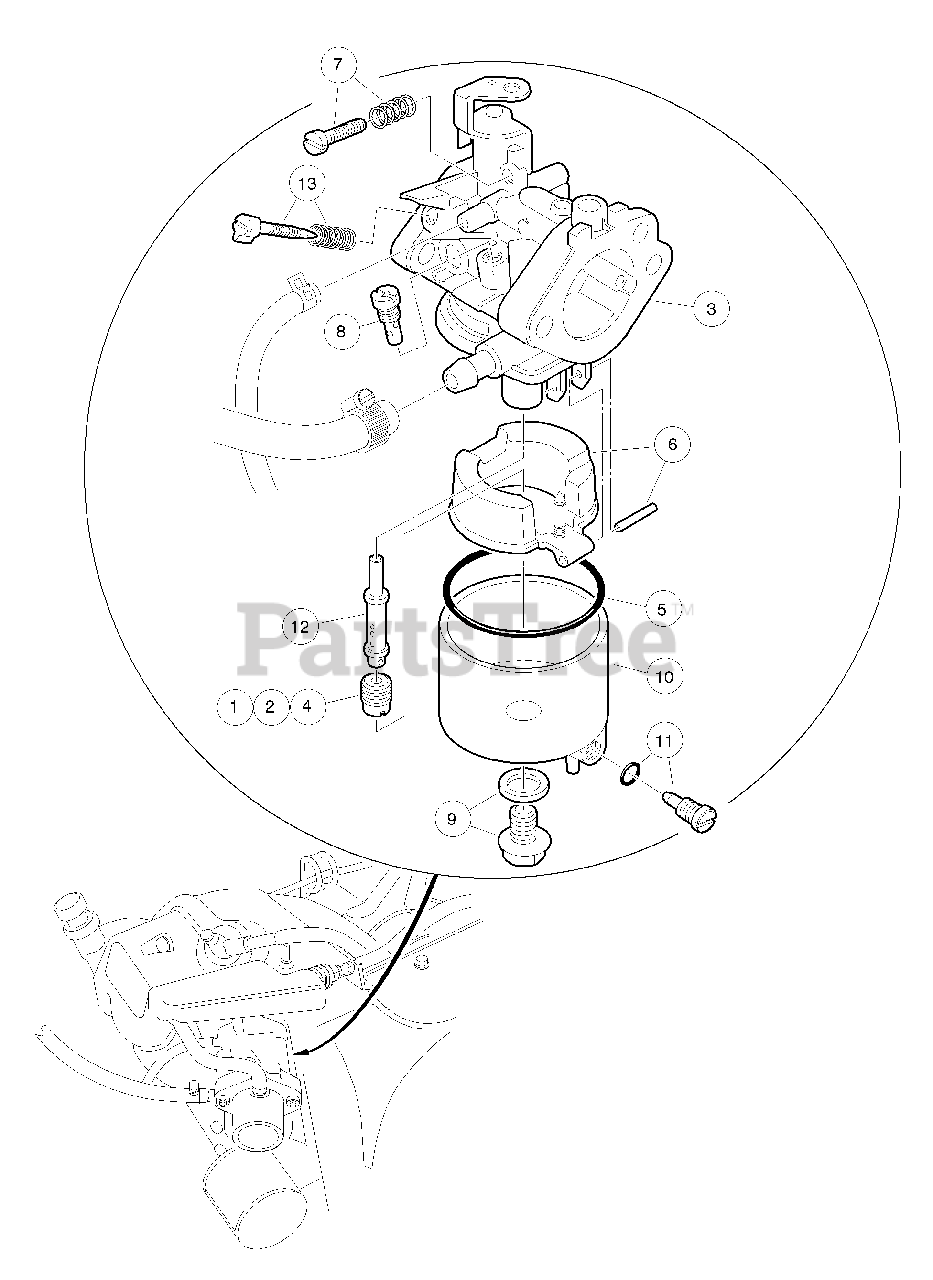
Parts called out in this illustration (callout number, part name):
1	Jet, Altitude, # 82
2	Jet, Altitude, # 85
3	Carburetor
5	Gasket, Carburetor Bowl OHV
6	Float Assembly
7	Screw Assembly
8	Jet #45 Pilot
10	Chamber Assembly, Float
11	Screw Assembly
12	Nozzle, Main, Carburetor
13	Assembly, Pilot Air Screw
